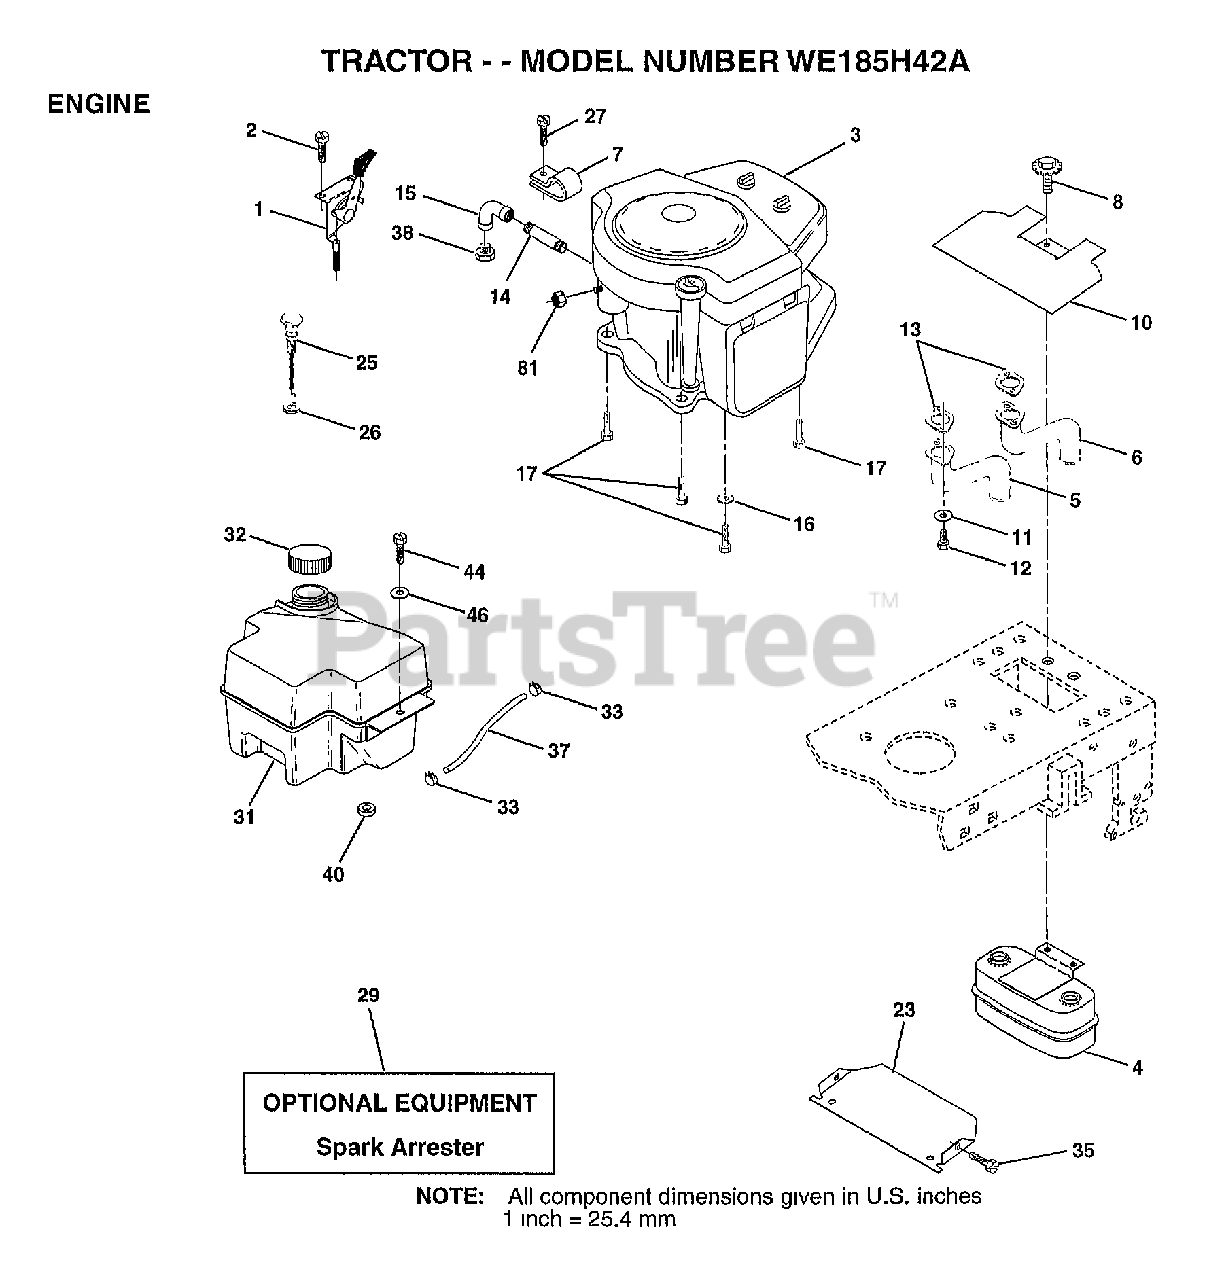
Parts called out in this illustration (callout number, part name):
1	CONTROL THRT 35.5
2	SCREW LT
3	ENGINE, BRIGGS
4	MUFFLER.TW.LOTONE
5	EXHAUST.B&S.18.LH
6	EXHAUST.B&S.18.RH
7	CLAMP.TUBE.DBL.EN
8	BOLT.5/16-18.UNC
10	SHIELD.HEAT.
11	LOCKWASHER
13	GASKET MUFFLER
14	PIPE NIPPLE LT
15	ELBOW
16	LOCKWASHER
17	SCREW LT
23	SHIELD-HEAT
25	CONTROL.CHOKE.37
26	"NUT,KEPS 3/8-24IM"
27	"SCREW-TT,10-32 FL"
32	CAP ASM FUEL
33	HOSE CLAMP
35	SCREW
37	LINE FUEL
44	SCREW HEX CRT
46	WASHER
81	NUT
